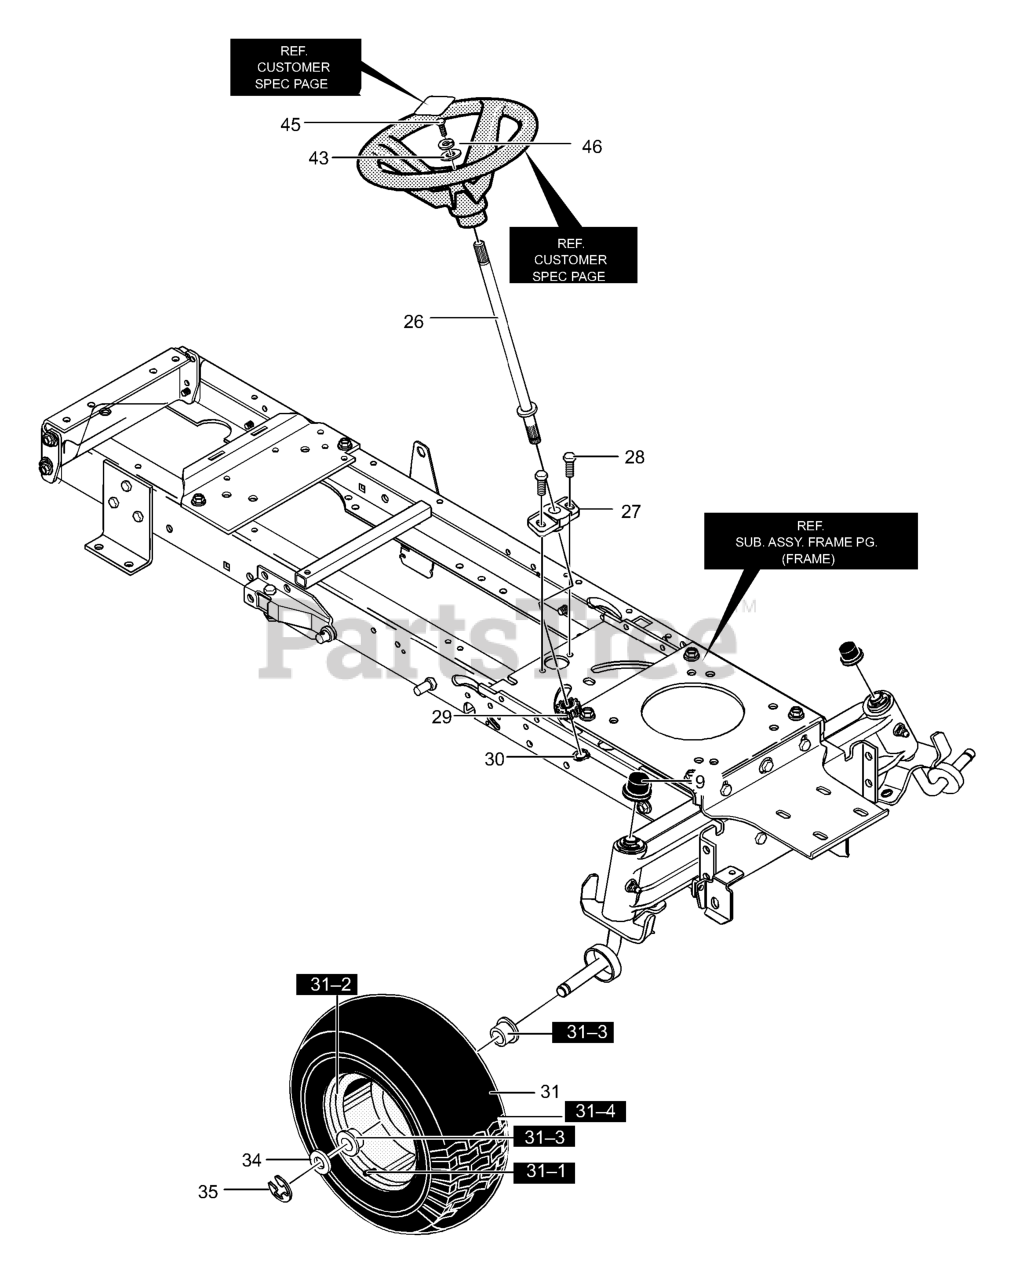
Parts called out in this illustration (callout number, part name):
9	HUB CAP
26	SHAFT, STEERING BOLT-ON
27	BEARING-LOWER
29	GEAR PINNION
30	RING, RETAINER
31	TIRE & RIM
31-1	VALVE STEM
31-3	BEARING
34	WASHER, FLAT
43	WASHER, FLAT
45	SCREW, 1/4-20X .75
46	WASHER, (18X32)
